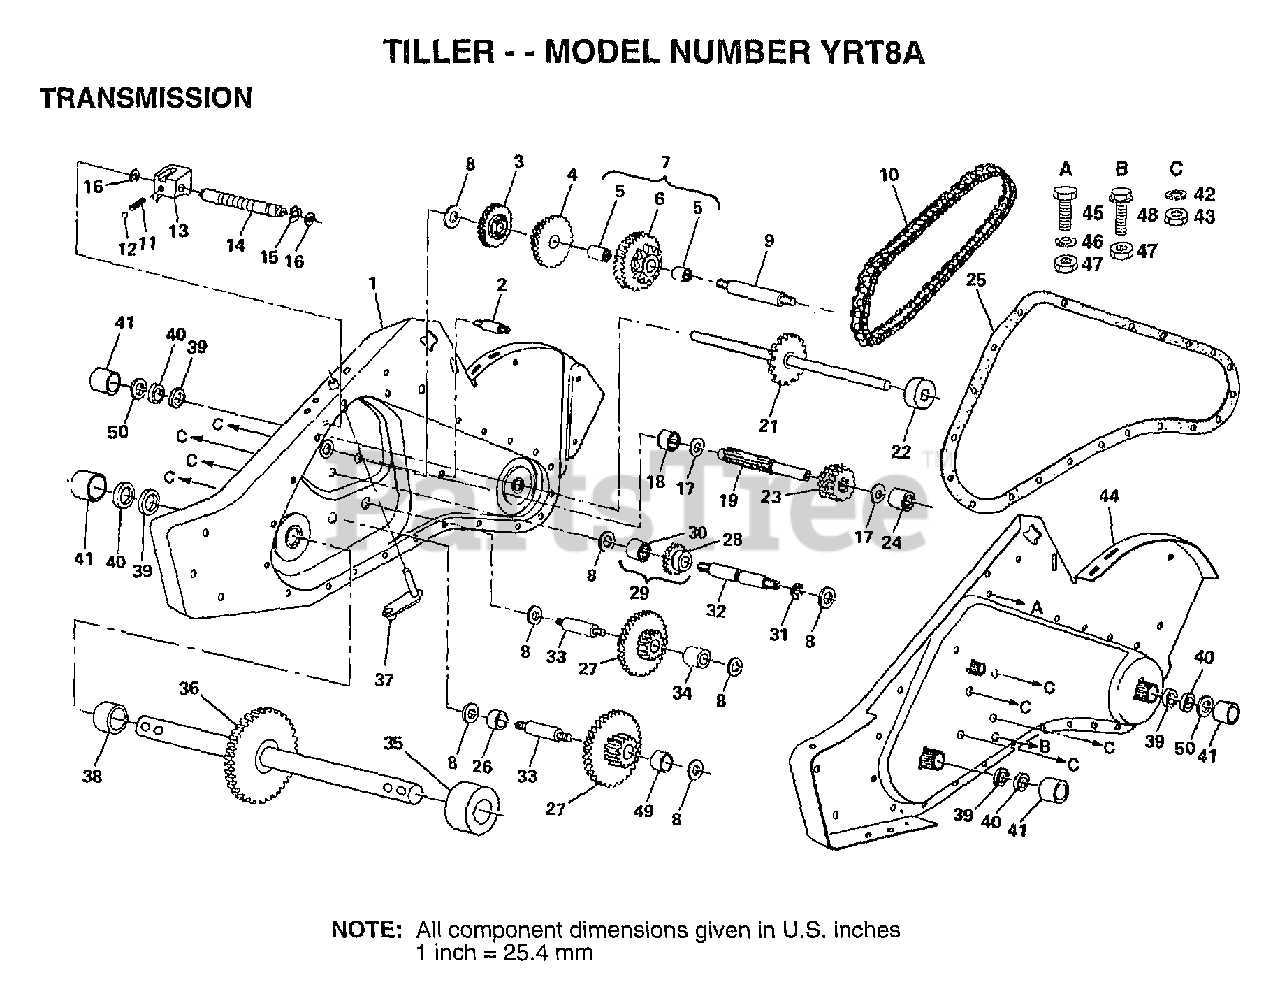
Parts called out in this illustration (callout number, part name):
2	BOLT TI
3	REVERSE GEAR TI
4	CLUSTER GEAR TI
5	"CRT, BEARING"
7	SPROCKET ASSY TI
8	WASHER
9	REDUCTION SHFT TI
10	CHAIN TI
11	SPRING-SHIFT CRT
13	SHIFT FORK TI
14	SHIFT SHAFT TI
15	KLIP RING
16	WASHER SEAL CRT
17	"T, BEARING"
18	"TI, BEARING"
19	SHAFT INPUT T
21	SHAFT TINE CRT
22	SPACER CRT
23	INPUT PINION TI
24	NEEDLE BRNG LT
25	GEARCASE GSKT TI
26	SPACER CRT
27	GEAR CLUSTER CRT
28	REVERSE GEAR TI
29	GEAR ASSY TI
30	NEEDLE BEARING TI
31	KLIP RING
32	REVERSE SHAFT TI
33	SHAFT CRT
34	SPACER CRT
35	SPACER CRT
36	SHAFT ASSY CRT
37	BRACKET ASM SHIFT
38	SPACER CRT
39	OIL SEAL STD
40	SEAL RING RUBBER
41	CUP.FORMED.
42	LOCKWASHER
43	NUT.ASF.HEX.7/16
45	BOLT
46	LOCKWASHER
47	NUT.HEX.5/16-18
48	BOLT TI
49	SPACER CRT
50	RING SPIRAL CRT
